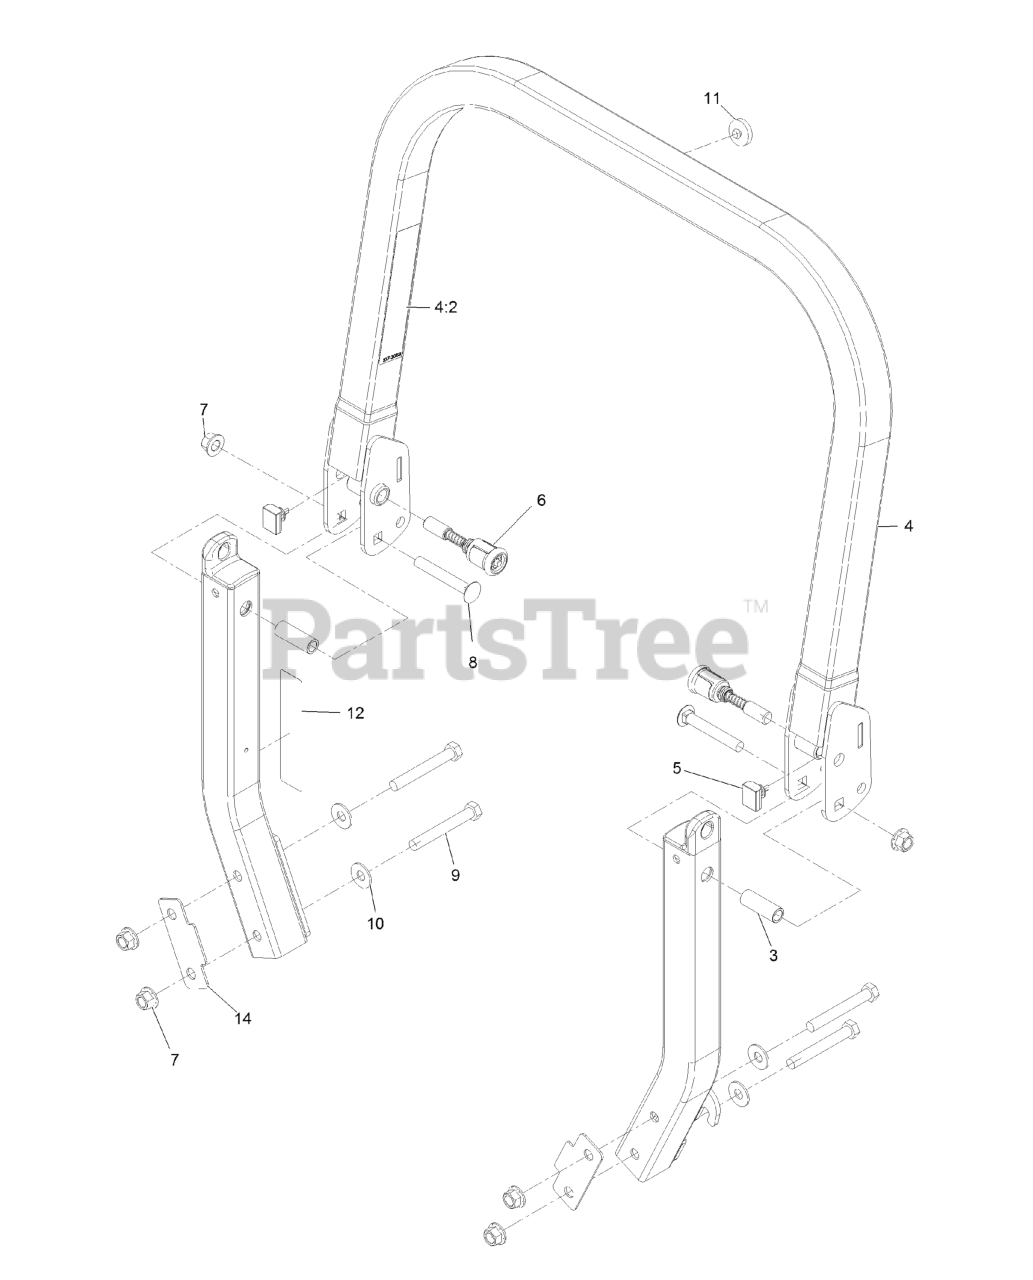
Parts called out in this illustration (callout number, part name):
4	UPPER ROPS ASM
4:2	DECAL-WARNING
5	BUMPER-ROPS
6	PIN-SPRING
7	Nut-Lock 1/2-13
8	SCREW-CARR
9	SCREW-HH
10	WASHER-SPRING
11	BUMPER-PUSH-IN, RUBBER
12	DECAL-CAUTION, FUEL VENT
